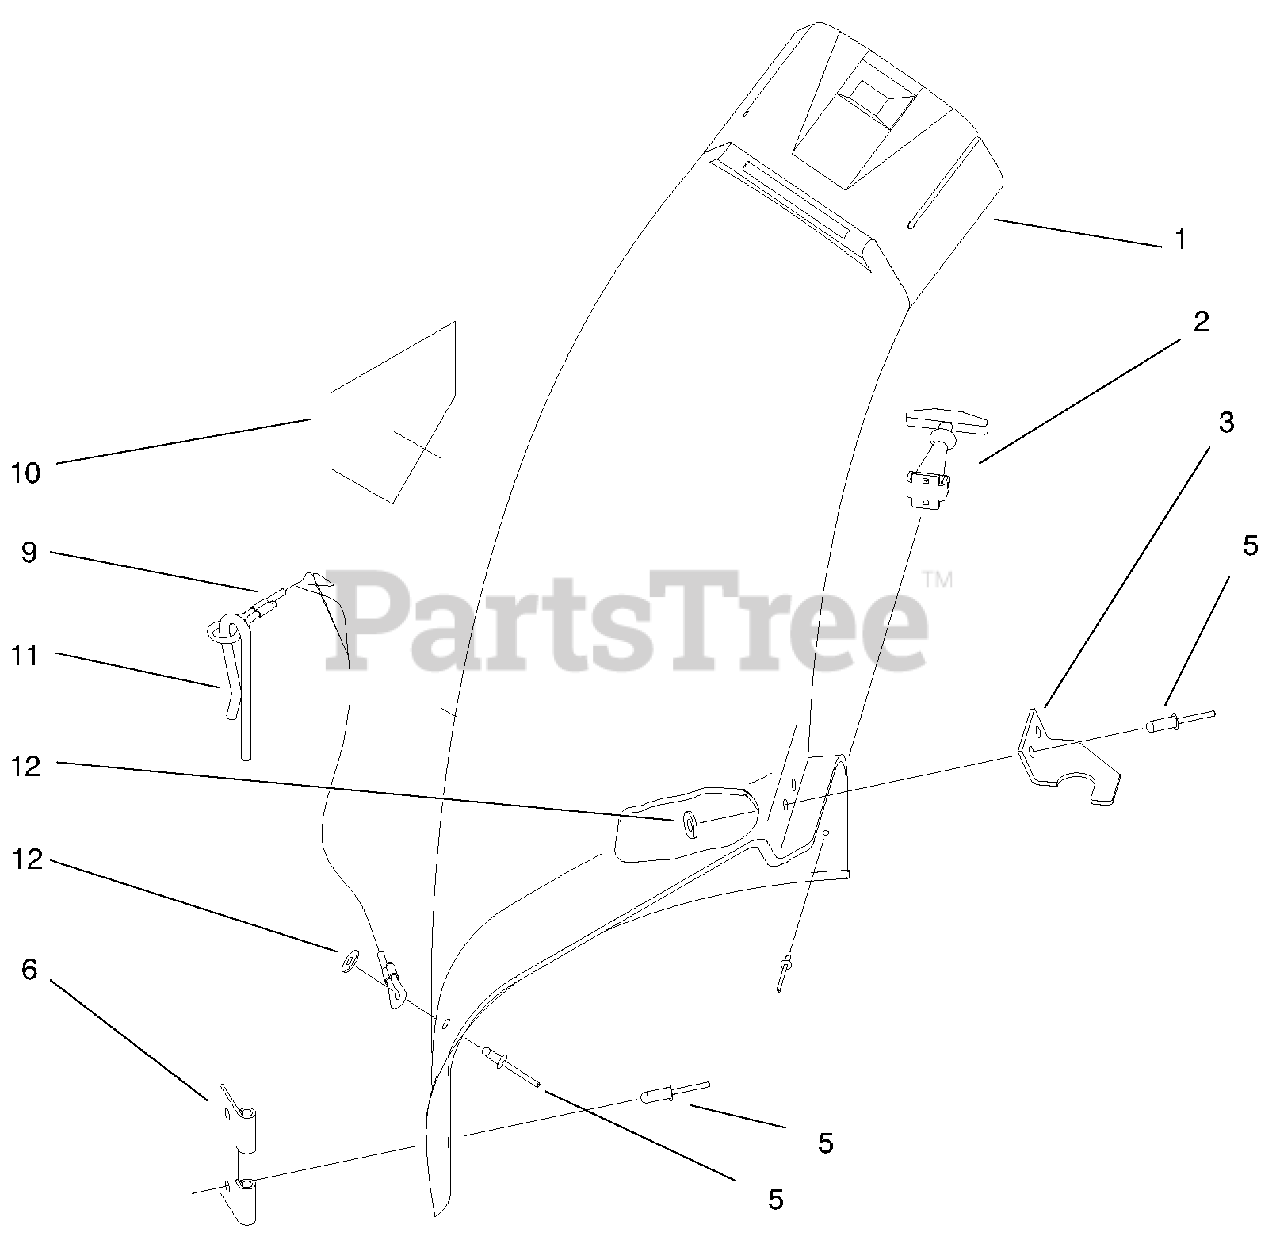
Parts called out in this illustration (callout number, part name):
1	ELBOW-BAGGER 38"
2	HANDLE ASM
3	LATCH-ELBOW, BAGGER
4	RIVET-POP
6	BRACKET-MOUNTING, CHUTE
10	DECAL-DANGER
11	PIN-LOCKING, CHUTE
12	WASHER-FLAT
